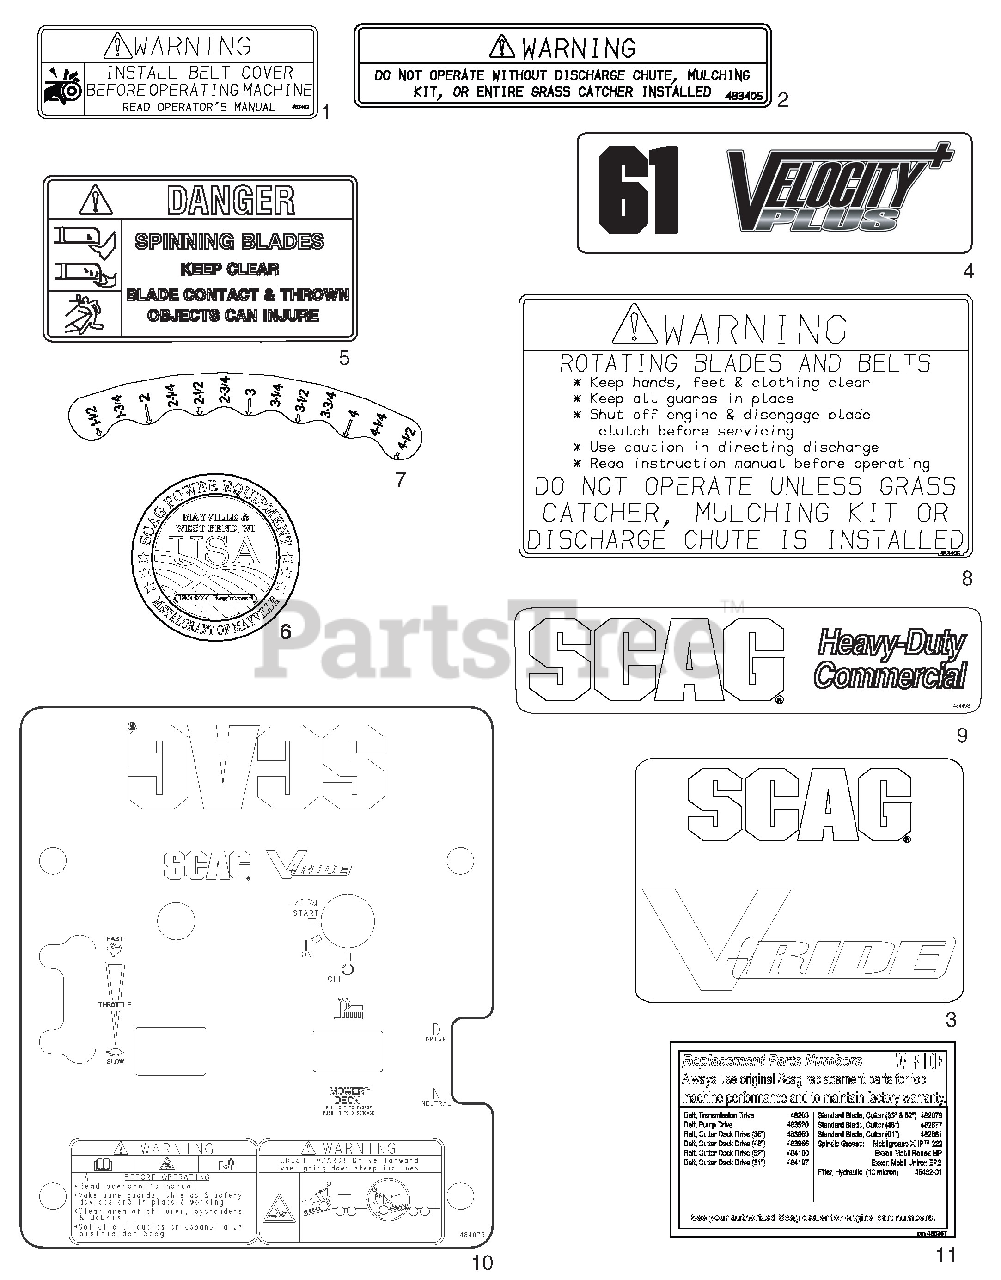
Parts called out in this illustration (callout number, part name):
1	Decal, Warning - Belt Cover
2	Decal, Warning
3	Decal, Belt Cover
3	Decal, Belt Cover - EFI
4	Decal, 36A
4	Decal, 48V
4	Decal, 52V
4	Decal, 61V
5	Decal, Spinning Blades
6	Decal, Metalcraft - USA
7	Decal, Height-of-Cut
8	Decal, Warning - Knives
9	Decal, Scag Heavy Duty Commercial
10	Decal, Instrument Panel
10	Decal, Instrument Panel - Recoil Start
10	Decal, Instrument Panel - EFI
11	Decal, SVR Replacement Parts
